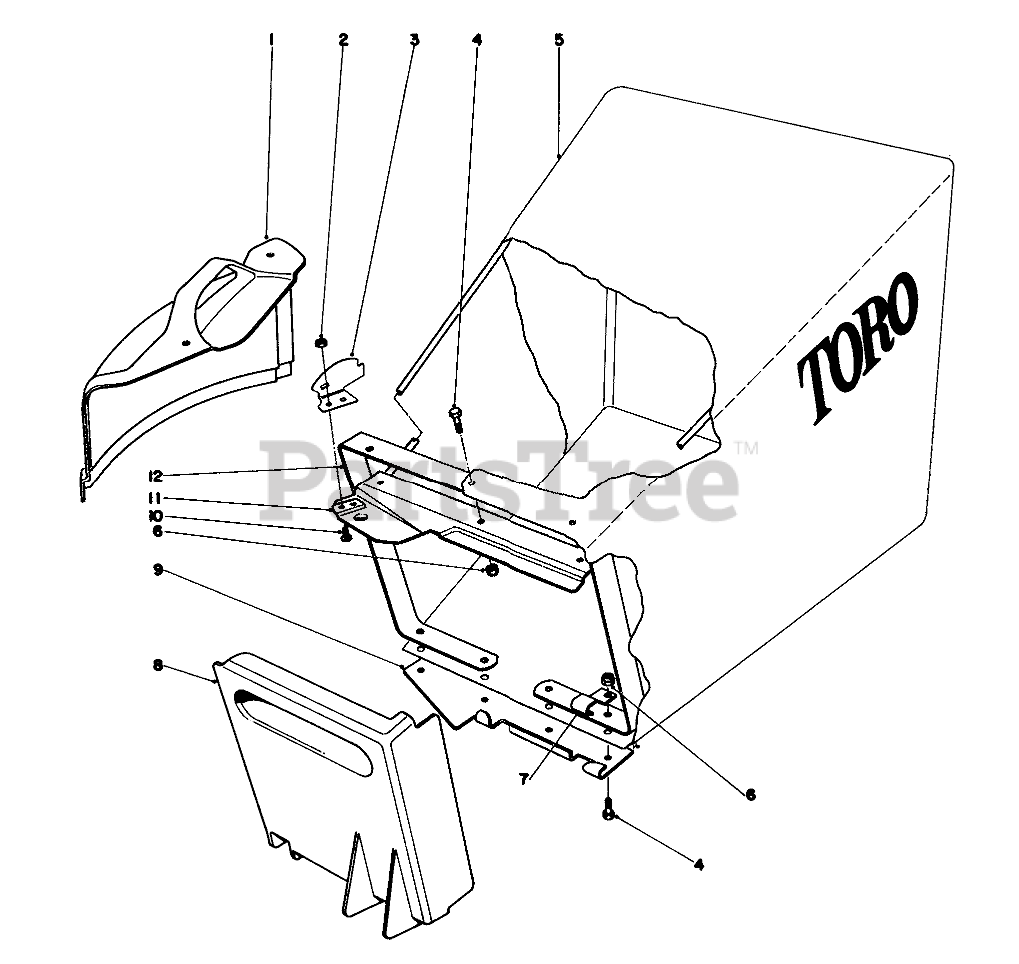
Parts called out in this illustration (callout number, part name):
1	Cover
2	NUT-LOCK
3	Latch Bag
4	SCREW-HWH
5	REPLACMNT BAG 44-0530
6	NUT-LOCK, SIDE
7	SUPPORT BRACKET
8	BAG DOOR
9	DOOR BRACKET
10	Screw
11	Bag Frame
12	LOWER BAG FRAME
